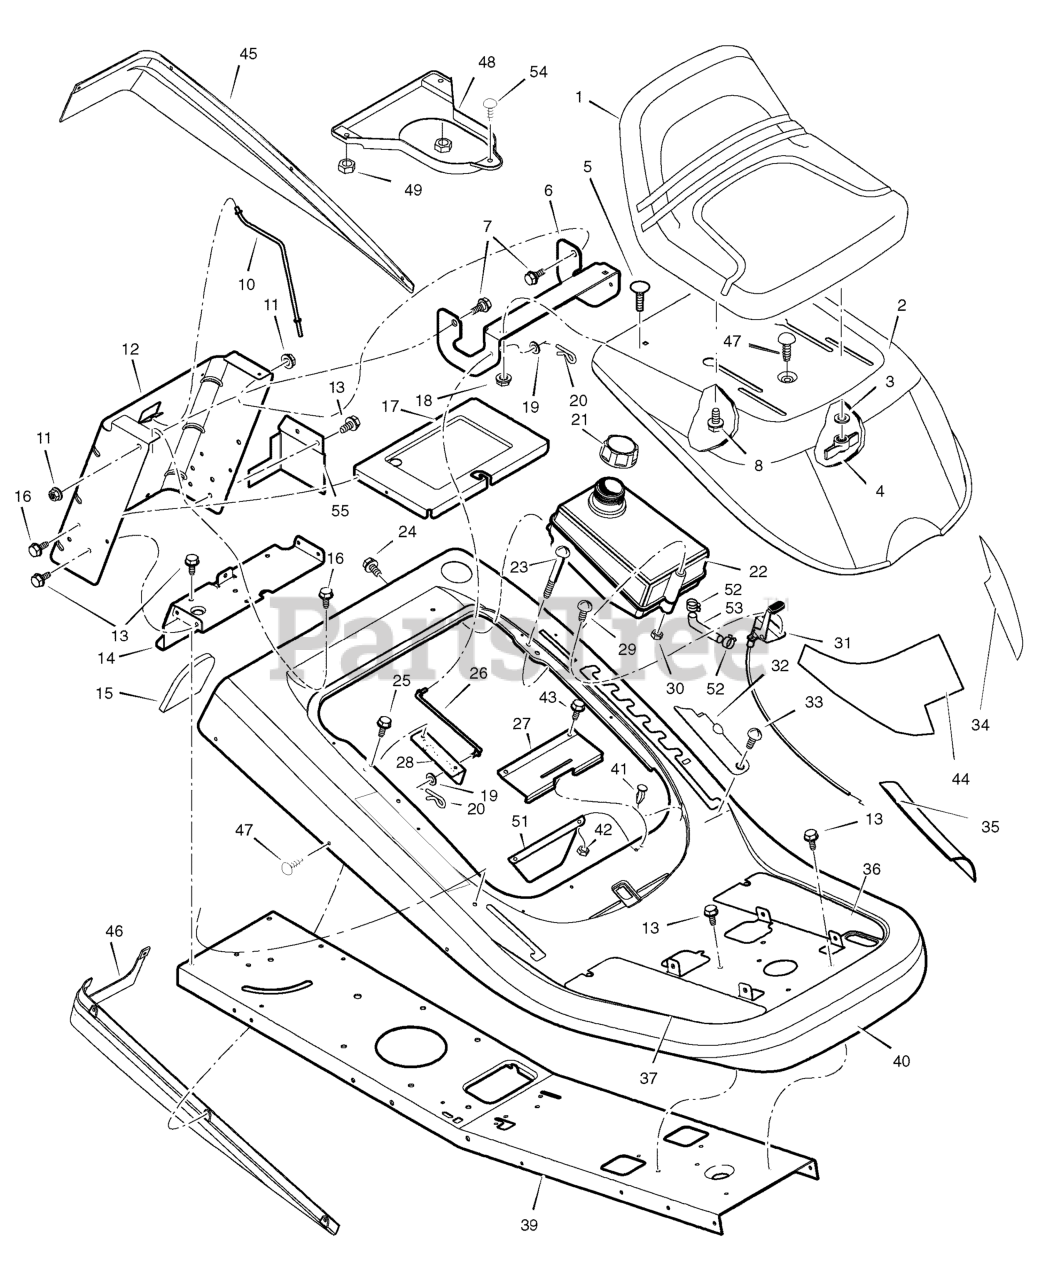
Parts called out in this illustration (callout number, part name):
1	SEAT
3	WASHER
4	BOLT, Wing
5	BOLT, Carriage
6	BRACKET, Hinge
7	BOLT, Shoulder
8	BOLT, Shoulder
10	ROD, Battery
11	NUT, Flange
12	PLATE, Rear
14	PLATE, Hitch
17	TRAY, Battery
18	NUT, Flange
20	PIN, Cotter
21	CAP, Fuel Tank
22	TANK, Fuel
26	ROD, Hood Prop
27	SPRING, Seat Deck
28	BRACKET, Prop Rod
30	NUT, Nylock
31	CONTROL, Throttle
32	COVER, Detent
33	BOLT, Shoulder
34	HEAT SHIELD, Hood L.H.
35	HEAT SHIELD, Hood Upper
36	FOOTMAT, Left
37	FOOTMAT, Right
42	NUT
43	SCREW
44	HEAT SHIELD, Hood R.H.
45	TRIM, Left
46	TRIM, Right (Gray)
47	PLUG PANEL, .25X.61L GR
49	NUT, Hex 5/16--18
51	HEAT SHIELD
52	CLAMP, Hose
53	LINE, Fuel
54	FASTENER, Panel
55	GUARD, Brake
